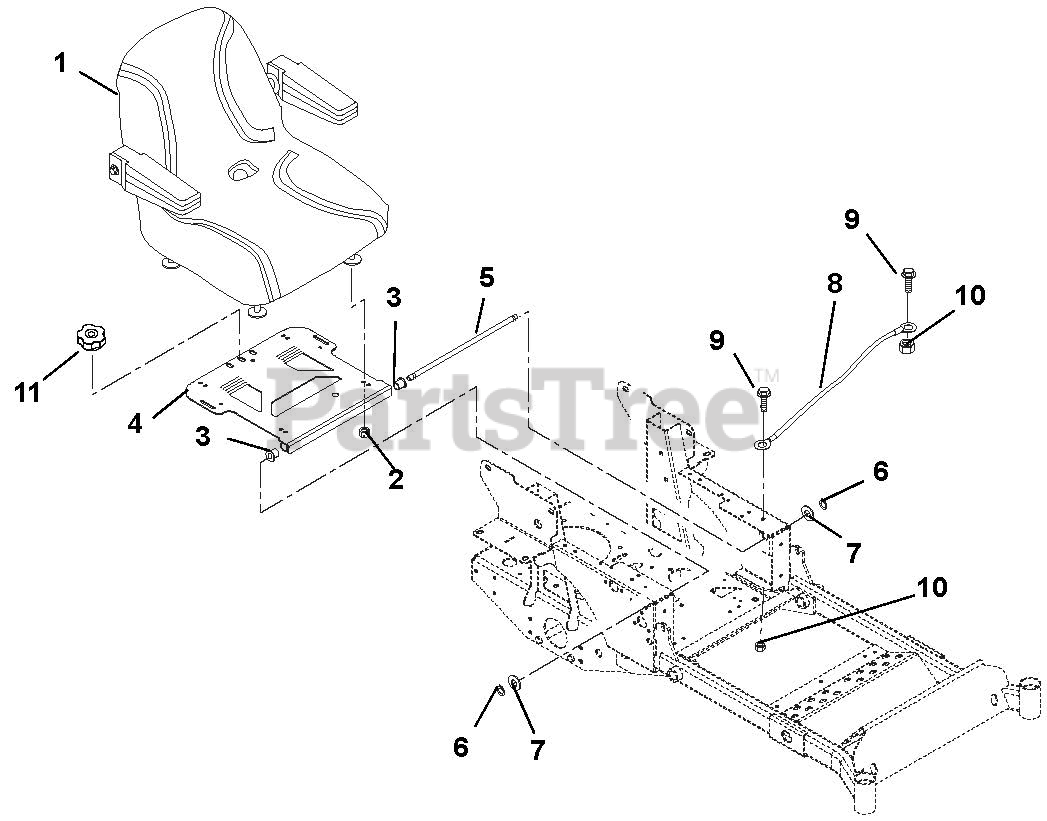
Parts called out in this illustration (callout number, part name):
2	Nut, Nyloc Flange .3125-18
3	Bushing, Flange .515 x .750 x .745 x 1.00
4	Seat Pivot Mount
5	Rod, Seat Frame Pivot
6	Ring, Retaining External .50 x .05
7	Washer, Flat Steel .531 x 1.00 x .063
8	Cable, Hood
9	Bolt, Hex .25-20 x .75 Grade 5
10	Nut, Nyloc Flange .25-20
11	Knob, Clamping .312-18
